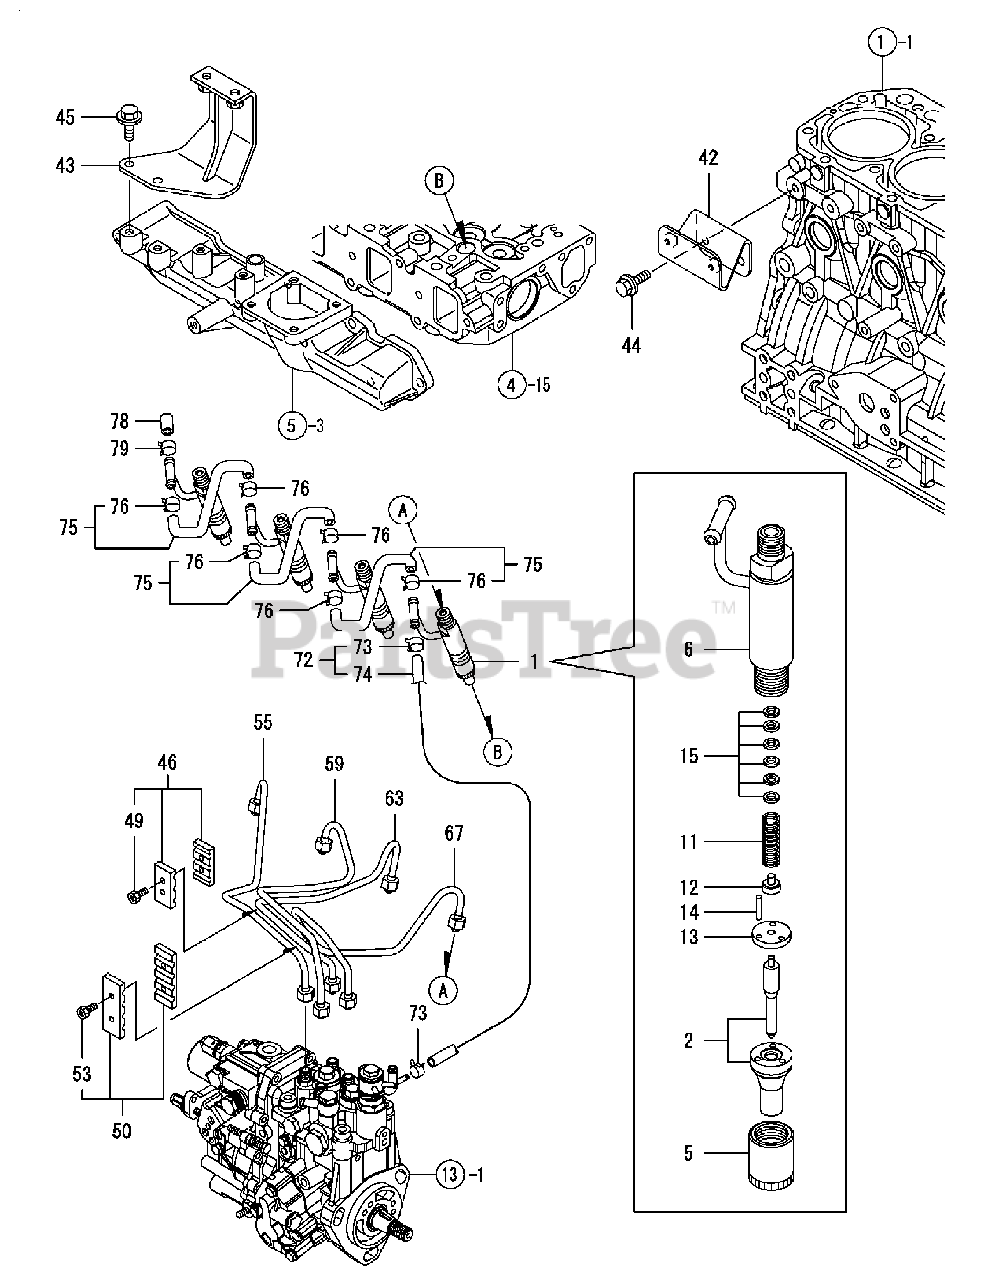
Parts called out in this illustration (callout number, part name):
1	VALVE ASSY,INJECTION
2	VALVE ASSY,INJECTION
6	HOLDER ASSY, NOZZLE
11	SPRING, NOZZLE
44	BOLT 8X 14 PLATED
45	BOLT M 8X 16 PLATED
46	RETAINER, PIPE
49	BOLT M4X14,HEX.SCKT.
50	RETAINER, PIPE
53	BOLT M4X14,HEX.SCKT.
55	PIPE ASSY, INJECTION
59	PIPE ASSY, INJECTION
63	PIPE ASSY, INJECTION
67	PIPE ASSY, INJECTION
72	PIPE ASSY, RETURN
74	PIPE, FUEL RETURN
75	PIPE ASSY, RETURN
79	CLAMP 10
